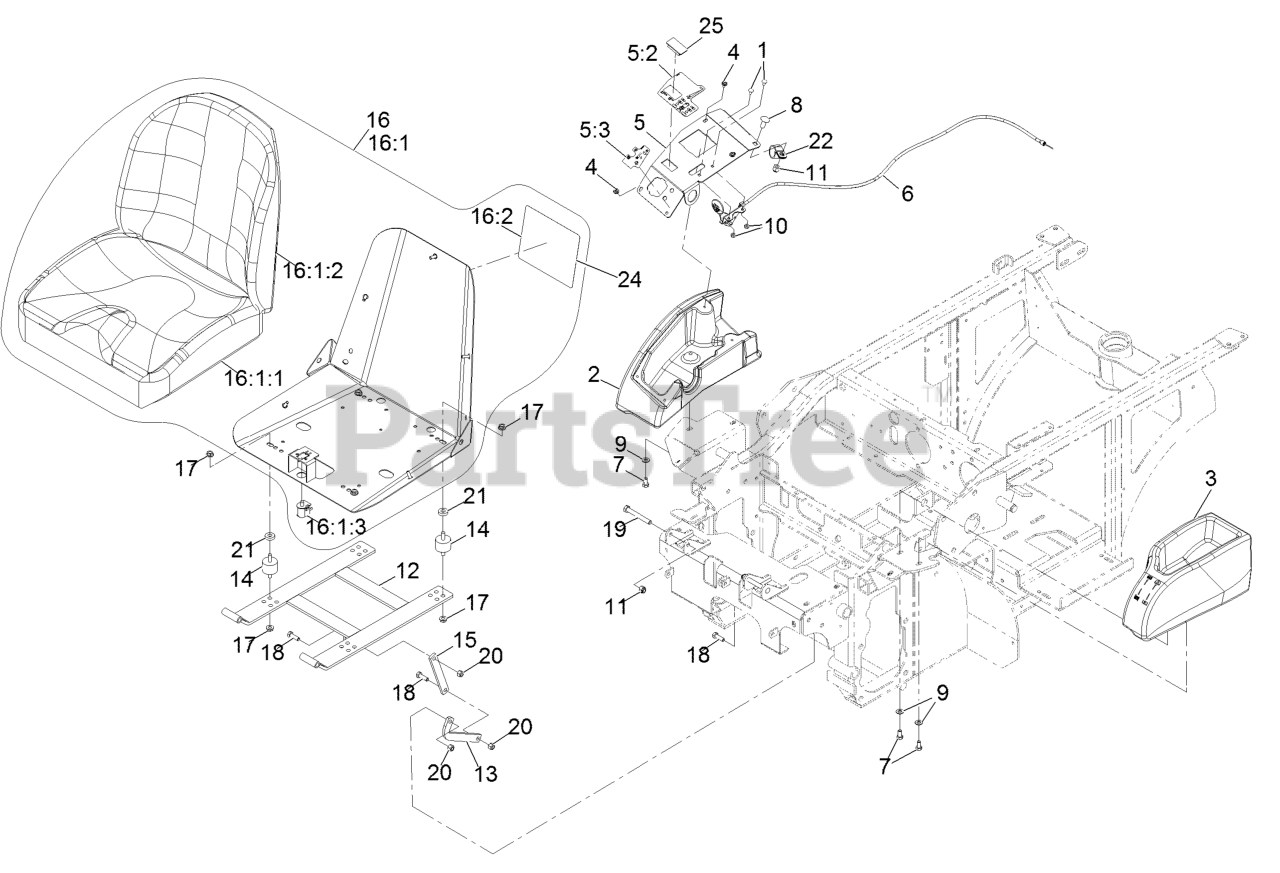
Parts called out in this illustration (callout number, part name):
1	BOLT-CARR
2	CONSOLE-RH
3	CONSOLE, LH GREY
4	SCREW-PPH
5	CONTROL PANEL ASM
5:2	Decal-Console
5:3	DECAL-SPEED CONTROL
6	CABLE-THROTTLE
7	SCREW-HH
8	SCREW-CARR
9	WASHER-PLAIN
10	NUT-LOCK, NI
11	NUT-LOCK, NI
12	FRAME-SEAT
13	LINK-SEAT STOP
14	MOUNT-VIBRATION, RUBBER
15	LINK-SEAT
16:1	Seat ASM
16:1:1	ASM-SEAT BOTTOM CUSHION
16:1:2	CUSHION,SEAT BACK
16:1:3	SWITCH-BAIL
16:2	Decal-Service Aid
18	SCREW-HH
19	SCREW-CARR
20	NUT-LOCK, NI
21	SPACER
22	CLIP-LOOM
24	Decal-Service Aid
25	PLUG-HOLE
